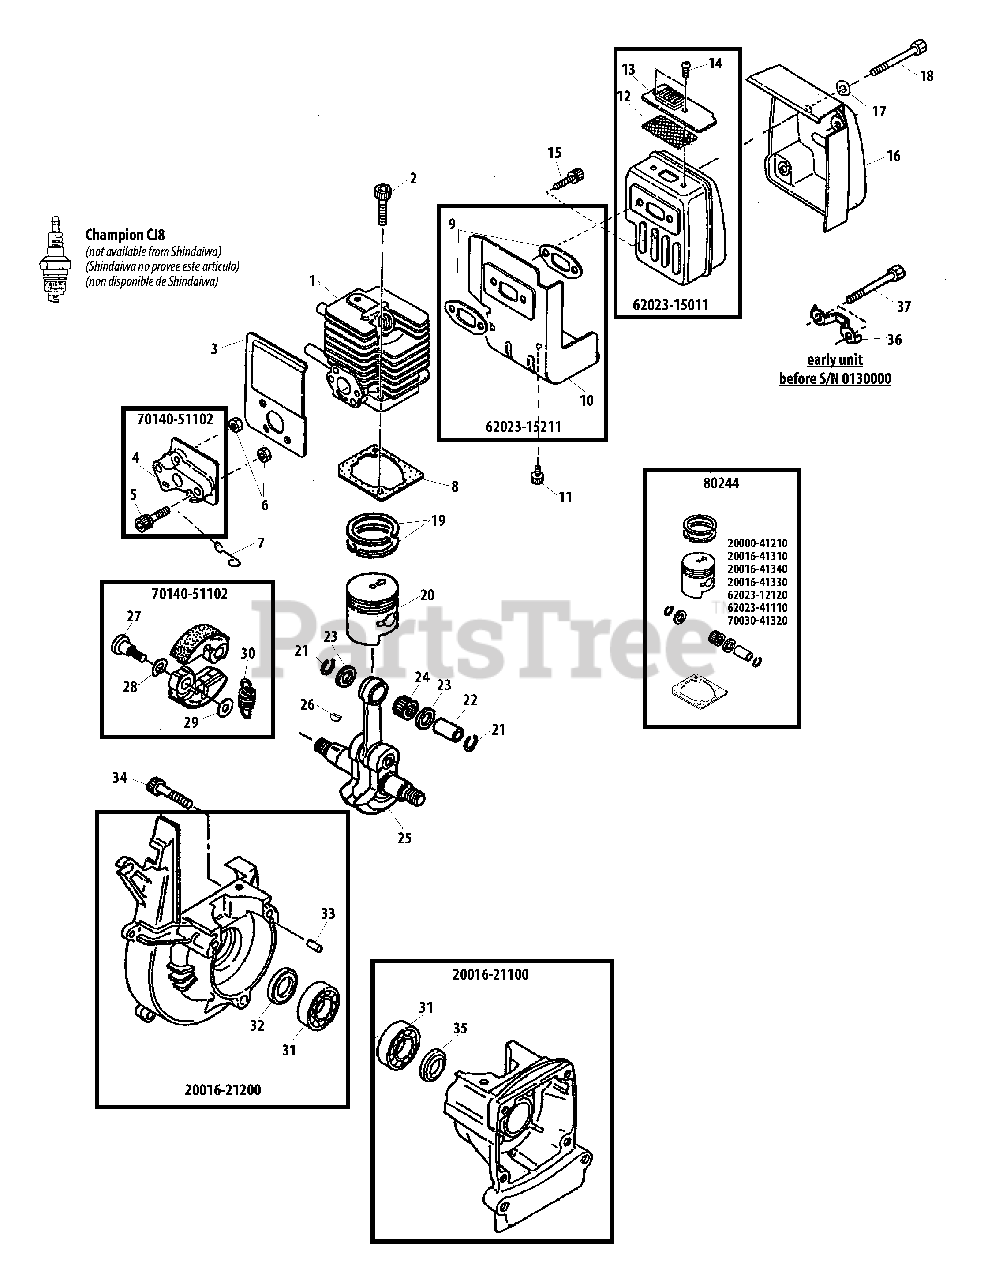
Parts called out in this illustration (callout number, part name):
1	CYLINDER
2	SCREW - 5X25
3	SHIELD, INTAKE
4	INSULATOR
5	SCREW - 5X30
6	NUT
7	HOLDER, VENT
8	GASKET, CYLINDER
9	SHIELD, EXHAUST
10	GASKET
11	SCREW - 5X8
12	SCREEN, SPARK ARRESTOR
13	TAIL PLATE
14	SCREW - 4X6
15	SCREW - 5X20
16	COVER, EXHAUST
17	WASHER - 5
18	SCREW - 5X60
19	RING, PISTON
20	PISTON
21	RING, RETAINING
22	PIN, PISTON
23	WASHER, THRUST
24	BEARING, NEEDLE
25	CRANKSHAFT ASSY
26	KEY - 3X10
27	BOLT, CLUTCH
28	WASHER - SPRING
29	WASHER - 6
30	SPRING, CLUTCH
31	BEARING, BALL - 6001C3
32	SEAL, OIL - 12
33	PIN - LOCATING
34	SCREW - 5X25
35	SEAL, OIL
36	PLATE, LOCK
37	BOLT
20016-21100	CRANKCASE ASSY - REAR
20016-21200	CRANKCASE ASSY - FRONT
62023-15011	MUFFLER ASSY
62023-15211	SHIELD, EXHAUST
70140-51102	CLUTCH ASSY
80244	PISTON ASSY
99909-12212	INSULATOR ASSY
